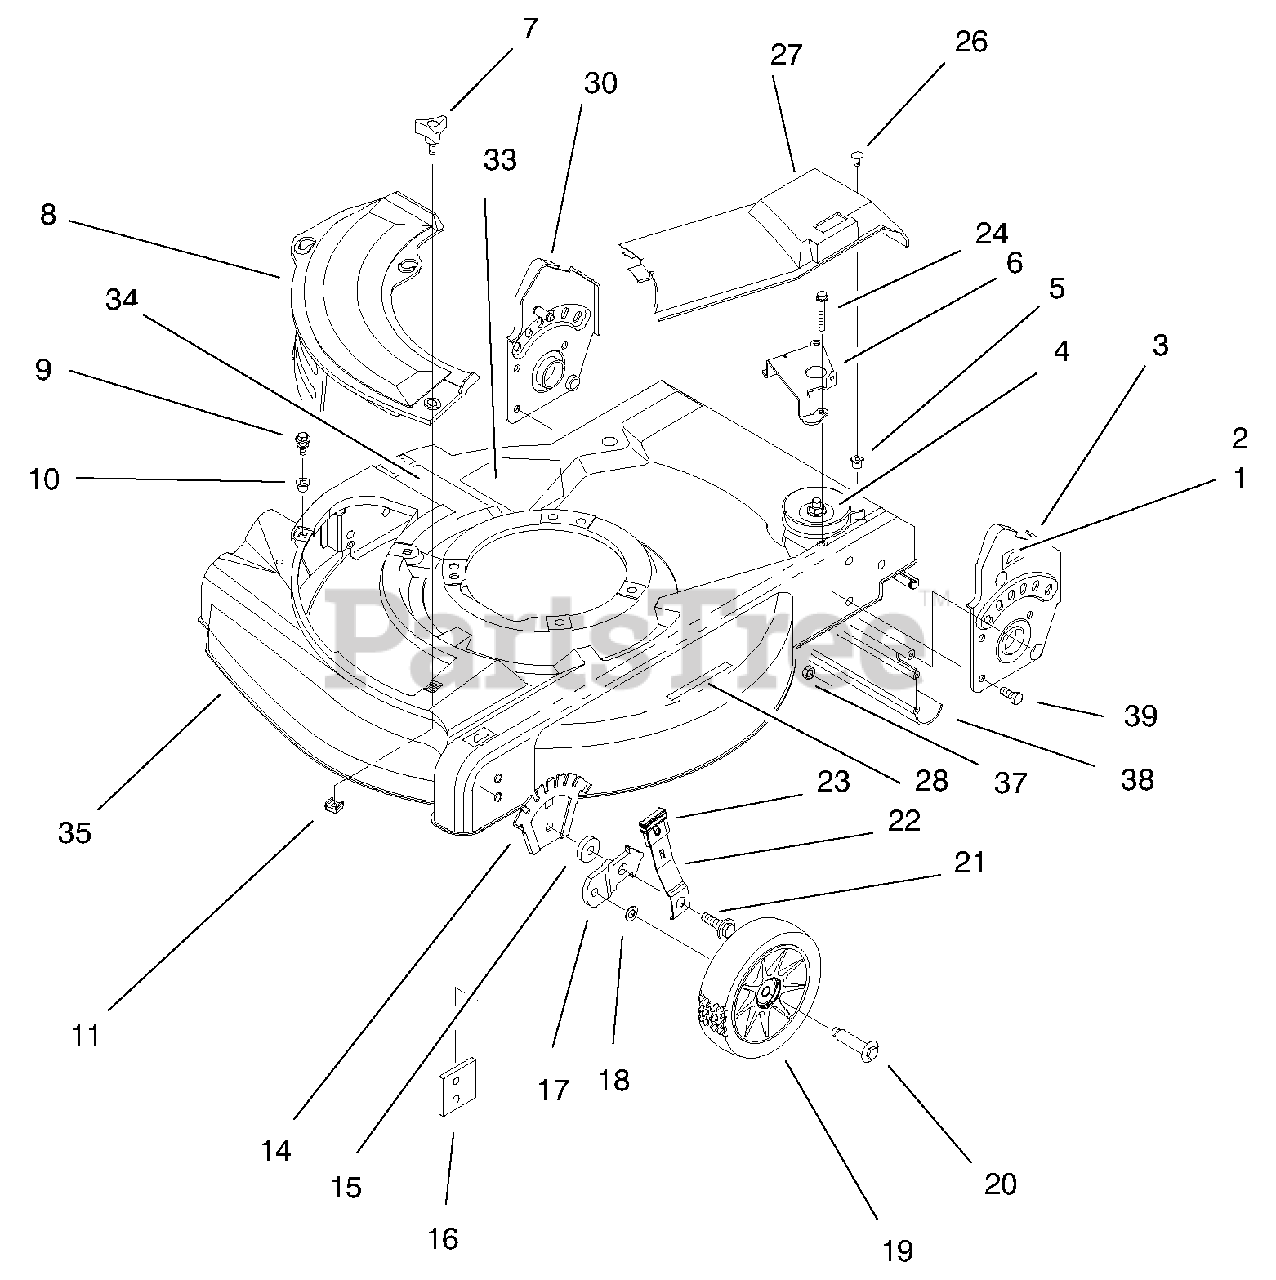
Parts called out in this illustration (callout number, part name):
1	Decal-HOC LH
2	Decal-HOC RH
3	ASM-Handle Bracket
4	ASM-Gear Case
5	Grommet
6	Guide-Transmission
7	Knob-Cover Plate
8	Mulch Plate-21"
9	Screw-Sems
10	Grommet-Plastic
11	Nut-Cage
14	Plate-Height Adjust
16	Plate-Baffle
17	Bracket-Wheel Height Adj
19	ASM-Wheel & Tire 6"
20	Bolt-Shoulder 6" Wheel
21	Bolt-Shoulder
22	Spring Arm-Front
23	Knob-Height Adjust
24	Screw-HH
26	Screw-Phil
27	Cover-Drive
28	Decal-Warning
30	ASM-Handle Bracket
33	Decal-Danger
34	Decal-Discharge
35	ASM-Housing & Baffle
37	Nut-Lock
38	Shield-Trailing
39	Screw-HH
